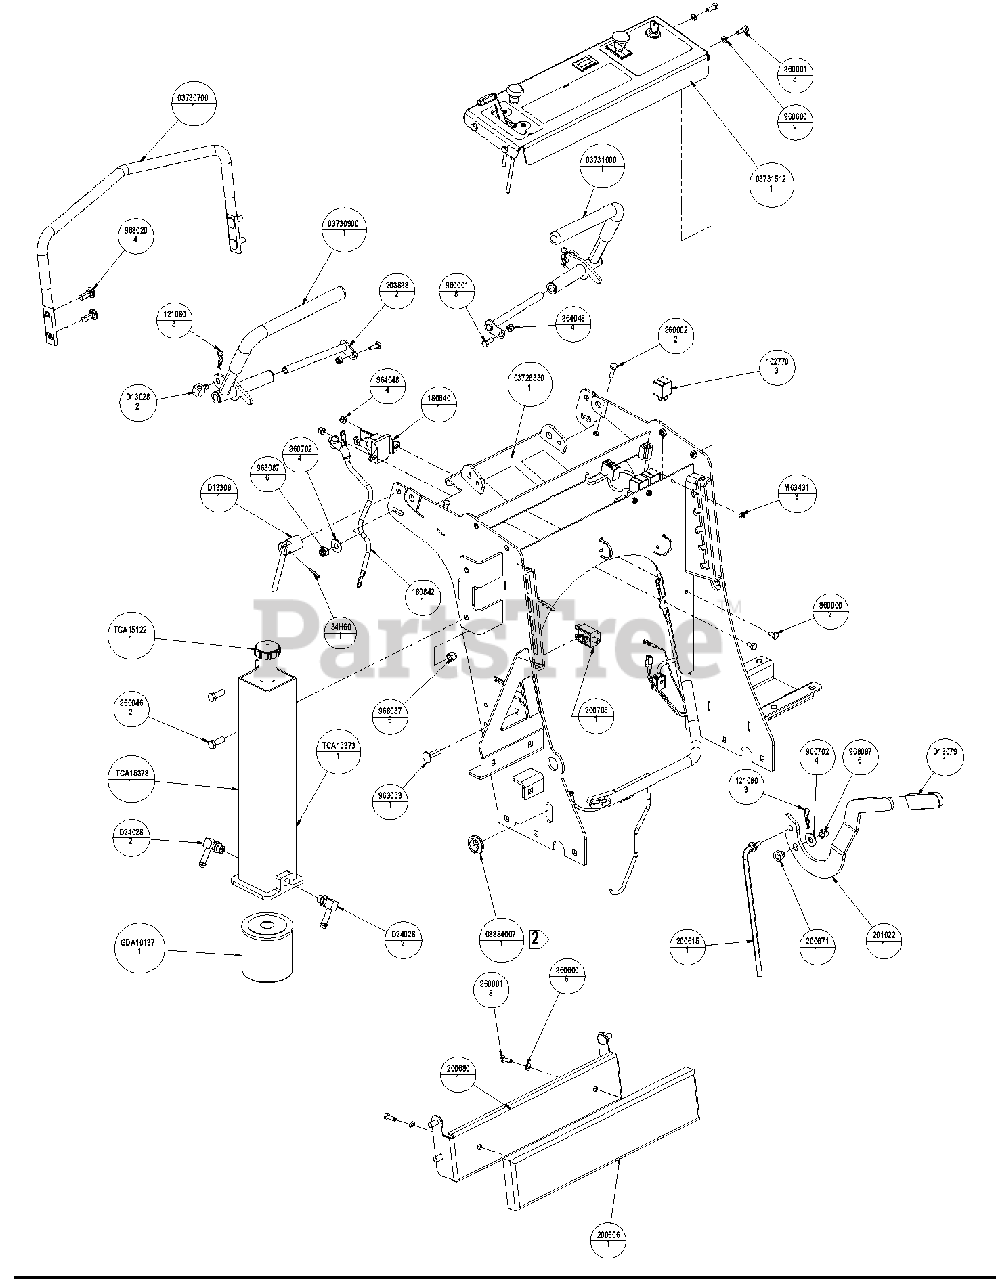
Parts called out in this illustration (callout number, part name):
1	SWIVEL ADJUSTER
2	BASE, LOCK LEVER Y
3	LEVER, LOCK Y
4	GRIP, PVC .250 X 1.00 X 3.63
5	SCREW, 8-32X .50 PAN PHL Y
6	FTG, 90 9/16 MOR X 3/8 HOSE
7	FITTING
8	FILTER, OIL
9	NUT, 8-32 ELASTIC STOP
10	CAP, FILLER OIL
11	WLDT, PIVOT ROD Y
12	WLDT, RESERVIOR HYDRAULIC
13	RELAY, ISO MINI ELEC.
14	CABLE TIE, .15 X 8.50
15	PIN, HAR .091 X 1.63 5/16-1/2 Y
16	SOLENOID, 12 V STARTER
17	CABLE, 12" STARTER
18	BRG, FLG .500X.620X.500 BRNZ
19	PAD, THIGH
20	LINK. BRAKE Y
21	CONTROL PANEL S/O
22	HANDLE, SUPPORT
23	BUSHING, BRAKE PIVOT Y
24	WLDT, THIGH PAD BRACKET
25	SWITCH, NO-NO-NC GREY PLUNGER
26	BRAKE LEVER, OFFSET
27	WLDT, CONSOLE 34
28	WLDT, RH CONTROL LEVER w/Grip
29	WLDT, LH CONTROL LEVER w/Grip
30	HARNESS, WIRING
31	FTG, 90 9/16 MOR X 3/8 HOSE
32	PIN, SPRING
33	BOLT, 1/4-20 X .500 HEX 5 Y
34	BOLT, 1/4-20 X .750 HEX 5 Y
35	BOLT, 1/4-20 X 1.00 HEX 5 Y
36	BOLT, 3/8-16 X 1.00 HEX 5 Y
37	NUT, 1/4-20 STD HEX GR5 Y
38	WASHER, .250 MED SPRG LOCK Y
39	WASHER, .375 REG FLAT Y
40	BOLT, 3/8-16 X 1.00 CRG 5 Y
41	BOLT, 3/8-16 X 1.25 CRG 5 Y
42	LOCKNUT, 1/4-20 NYLOC Y
43	LOCKNUT, 3/8-16 NYLOC Y
